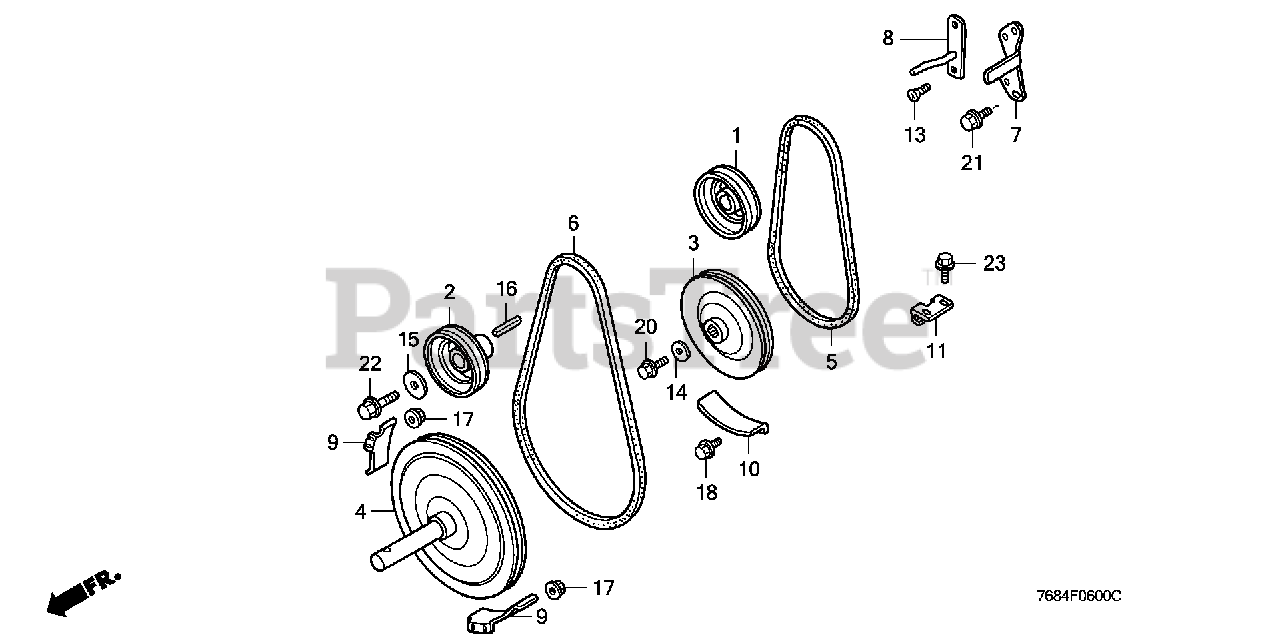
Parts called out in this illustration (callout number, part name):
1	PULLEY, WHEEL DRIVE
2	PULLEY, AUGER DRIVE
3	PULLEY, WHEEL DRIVEN (133MM)
4	PULLEY, AUGER DRIVEN (198MM)
5	V-BELT (SA-29)
6	V-BELT (SB-35)
7	STOPPER, R. BELT
8	STOPPER, L. BELT
9	STOPPER, AUGER BELT
10	PROTECTOR, BELT (WHEEL)
11	GUIDE, BELT
13	BOLT, LOCK STRIKER
14	WASHER, CAMSHAFT SIDE
15	WASHER, LOCK (8MM)
16	KEY (7X7X33) (OVER SIZE) (YELLOW)
17	NUT, FLANGE (6MM)
18	BOLT, FLANGE (6X12)
20	BOLT, FLANGE (6X16)
21	BOLT, FLANGE (8X16)
22	BOLT, FLANGE (8X28)
23	BOLT, FLANGE (6X12)
